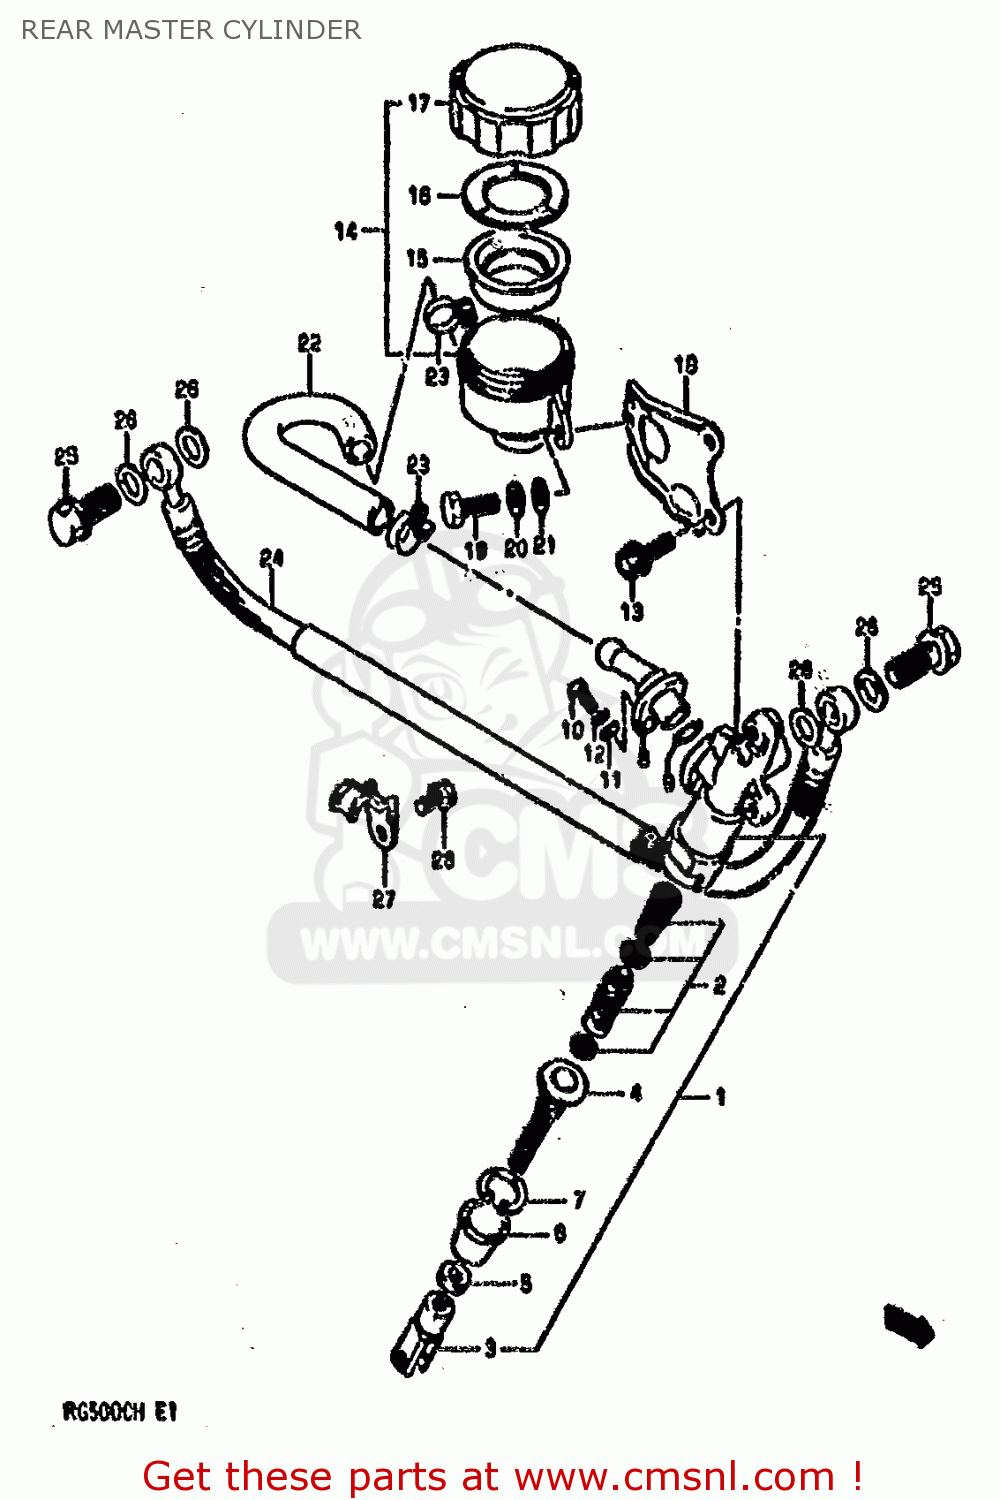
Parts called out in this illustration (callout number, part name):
1	CYLINDER ASSY,REAR MASTER
2	PISTON/CUP SET
3	YOKE
4	ROD,PUSH
5	NUT,MASTER CYLINDER
6	BOOT
7	CIRCLIP
8	CONNECTOR
9	O RING
10	SCREW
11	WASHER
12	LOCK WASHER
13	PLUG ,6X20
14	TANK ASSY,RESERVOIR
15	DIAPHRAGM
16	PLATE,DIAPHRAGM
17	CAP
18	PLATE RESERVOIR TANK
19	BOLT
20	WASHER,LOCK
21	WASHER
22	HOSE,RESERVOIR TANK
23	CLAMP
24	HOSE,REAR BRAKE
25	BOLT UNION
26	WASHER(10X15X1.5)
27	CLAMP,REAR BRAKE HOSE
28	BOLT
